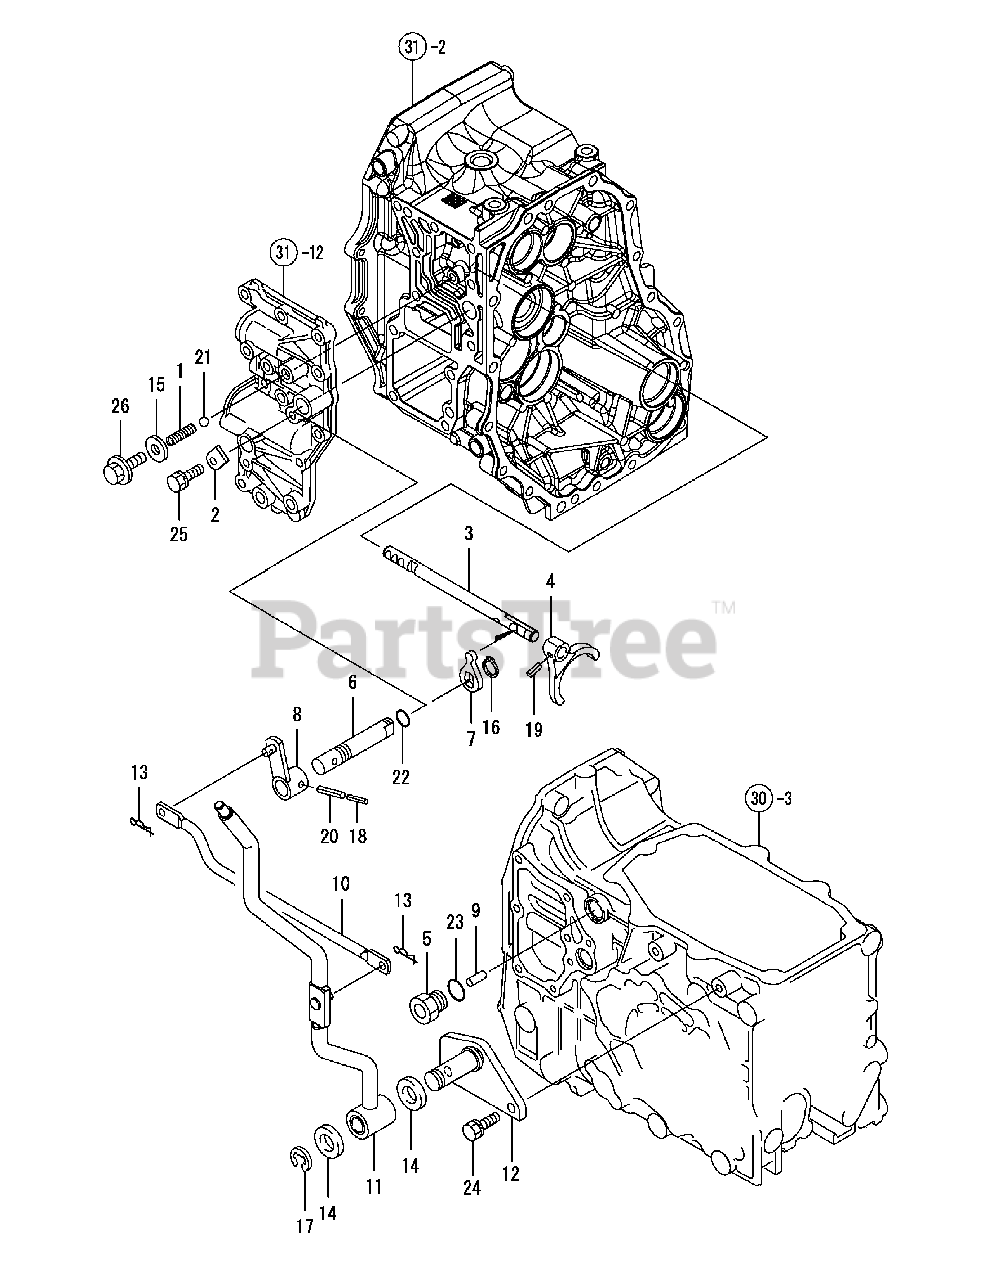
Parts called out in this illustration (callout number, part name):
3	Shaft, PTO Fork
4	Fork,PTO Shift
5	Holder M20,Switch
6	Shaft,PTO Shift
8	Arm,Cmp PTO Shift
9	Pin,Switch PTO
10	Shift, PTO Shift
11	Lever Cmp, PTO
12	Bracket, PTO Lever
13	Pin 8, Come-Off Snap
15	Seal Washer 10(Bolt)
18	Spring Pin 3.5X32
19	Spring Pin 6X20
20	Spring Pin 6X32
21	Ball 5/16, Steel
22	O-Ring 1A P-12.5
23	O-Ring 1A P-18.0
26	Bolt M10X 25 Plated
